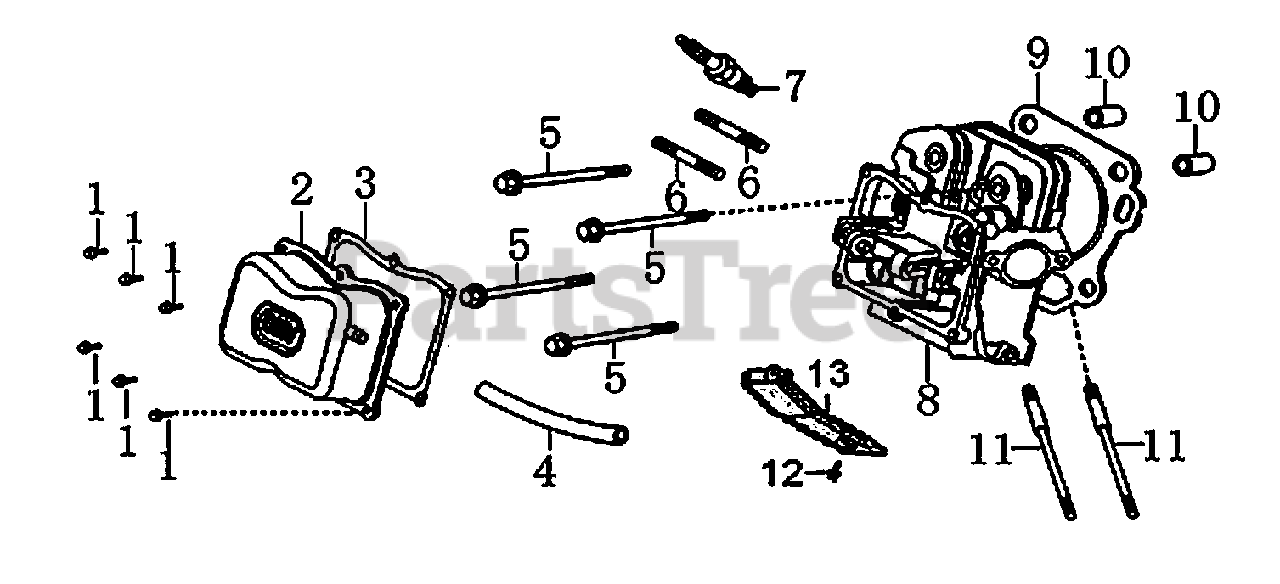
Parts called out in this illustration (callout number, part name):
1	BOLT' FLANGE
2	COVER COMP. HEAD
3	GASKET' VALVE COVER
4	TUBE' BREATHER
5	BOLT' FLANGE' 10×80
6	BOLT' STUD' EXHAUST
7	SPARK PLUG
8	CYLINDER HEAD COMP
9	GASKET' CYLINDER
10	PIN' DOWEL
11	BOLT' STUD' INTAKE
12	BOLT' FLANGE M6×12
